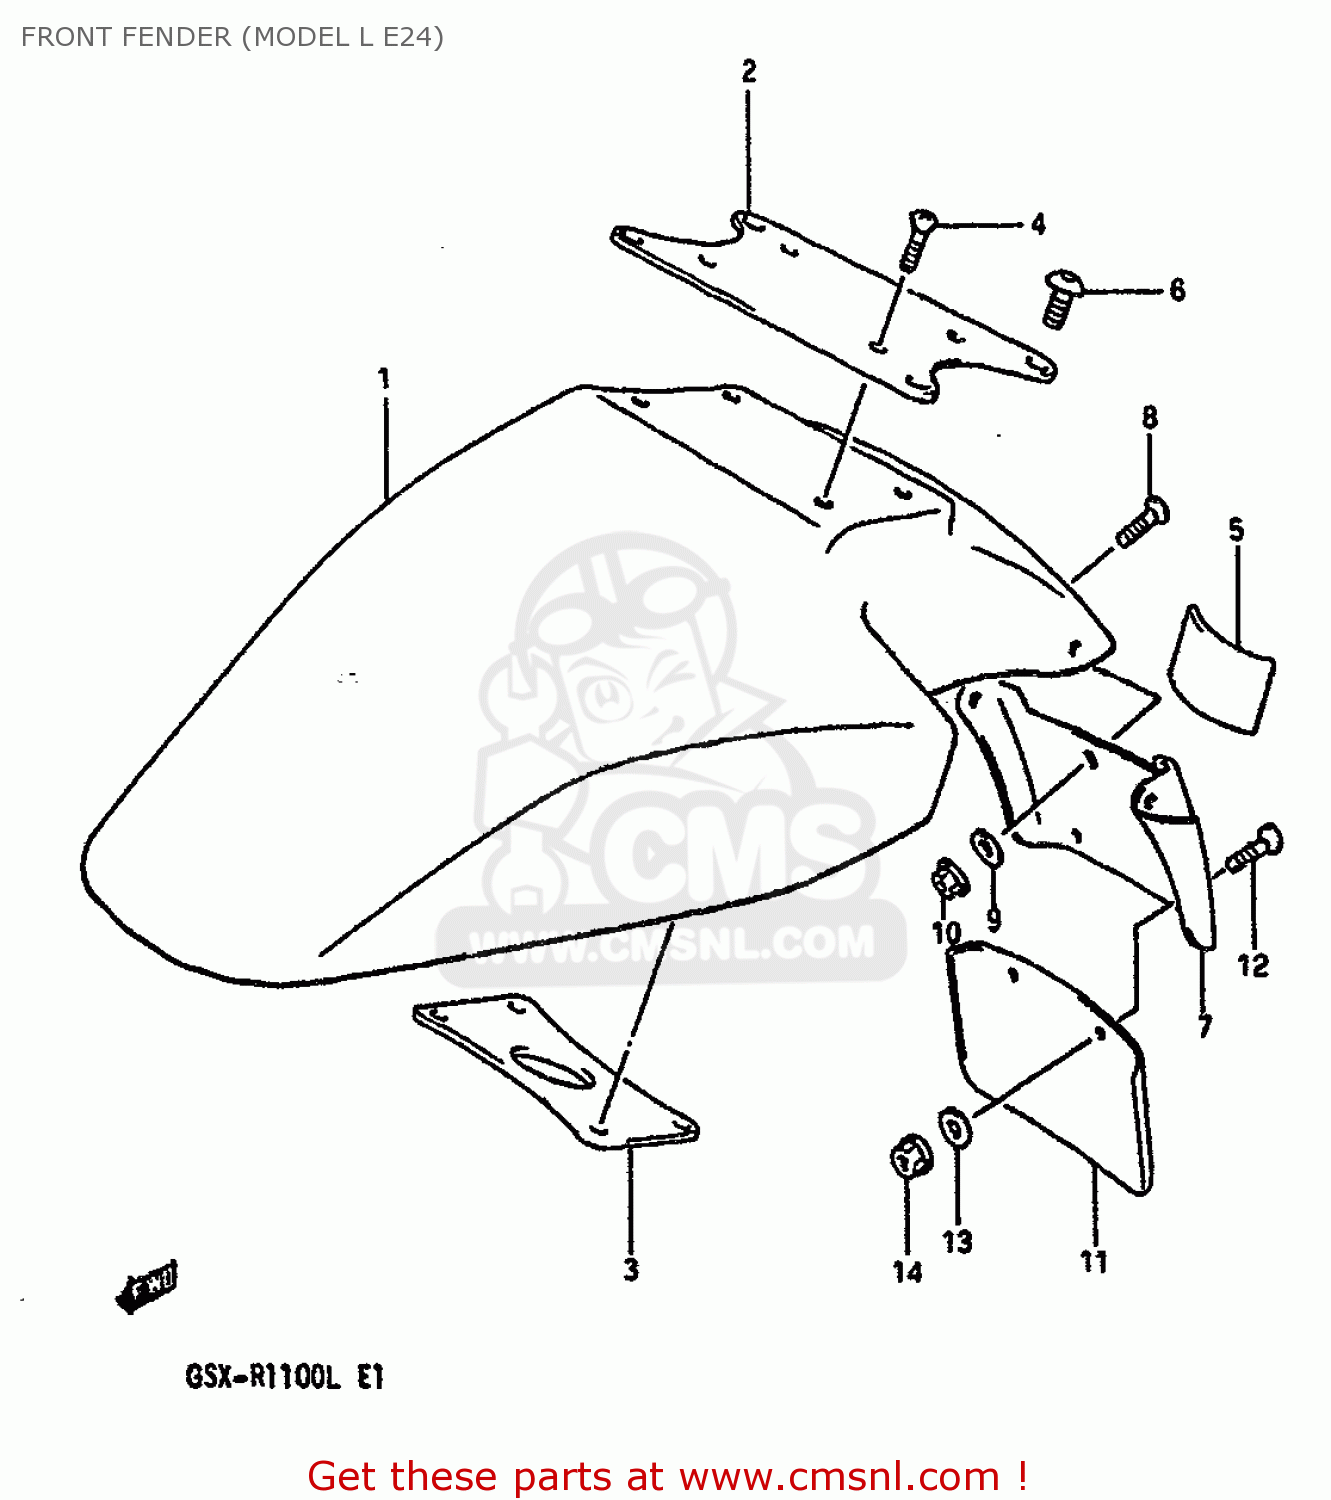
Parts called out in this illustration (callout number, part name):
1	FENDER,FR
2	BRACE,FR FENDER
3	BRACE,FR FENDER INNER
4	SCREW(5X18)
5	CUSHION,FR FENDER
6	SCREW(8X16)
7	MUD GUARD,UPPER
8	SCREW, FRONT & REAR
9	WASHER
10	NUT 5MM
11	MUD GUARD,FR.F
12	SCREW, FRONT & REAR
13	WASHER
14	NUT 5MM
